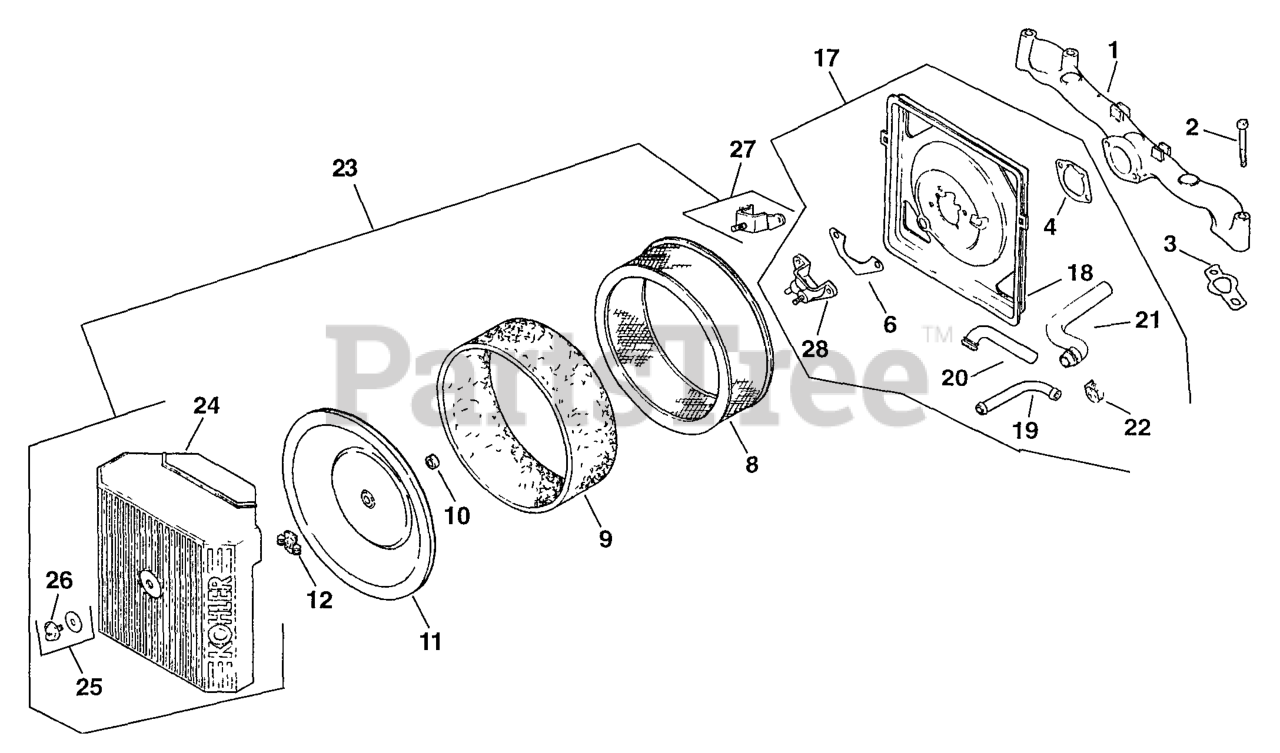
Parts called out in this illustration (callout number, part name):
1	Manifold, Intake
2	Screw, Hex. Flange M6x1.0x55
3	Gasket, Intake Manifold
4	Gasket, Air Cleaner Base
12	Nut, Wing
25	Kit, Air Cleaner Knob W/ Gasket
26	Knob, Air Cleaner Cover
27	Bracket, Air Cleaner
